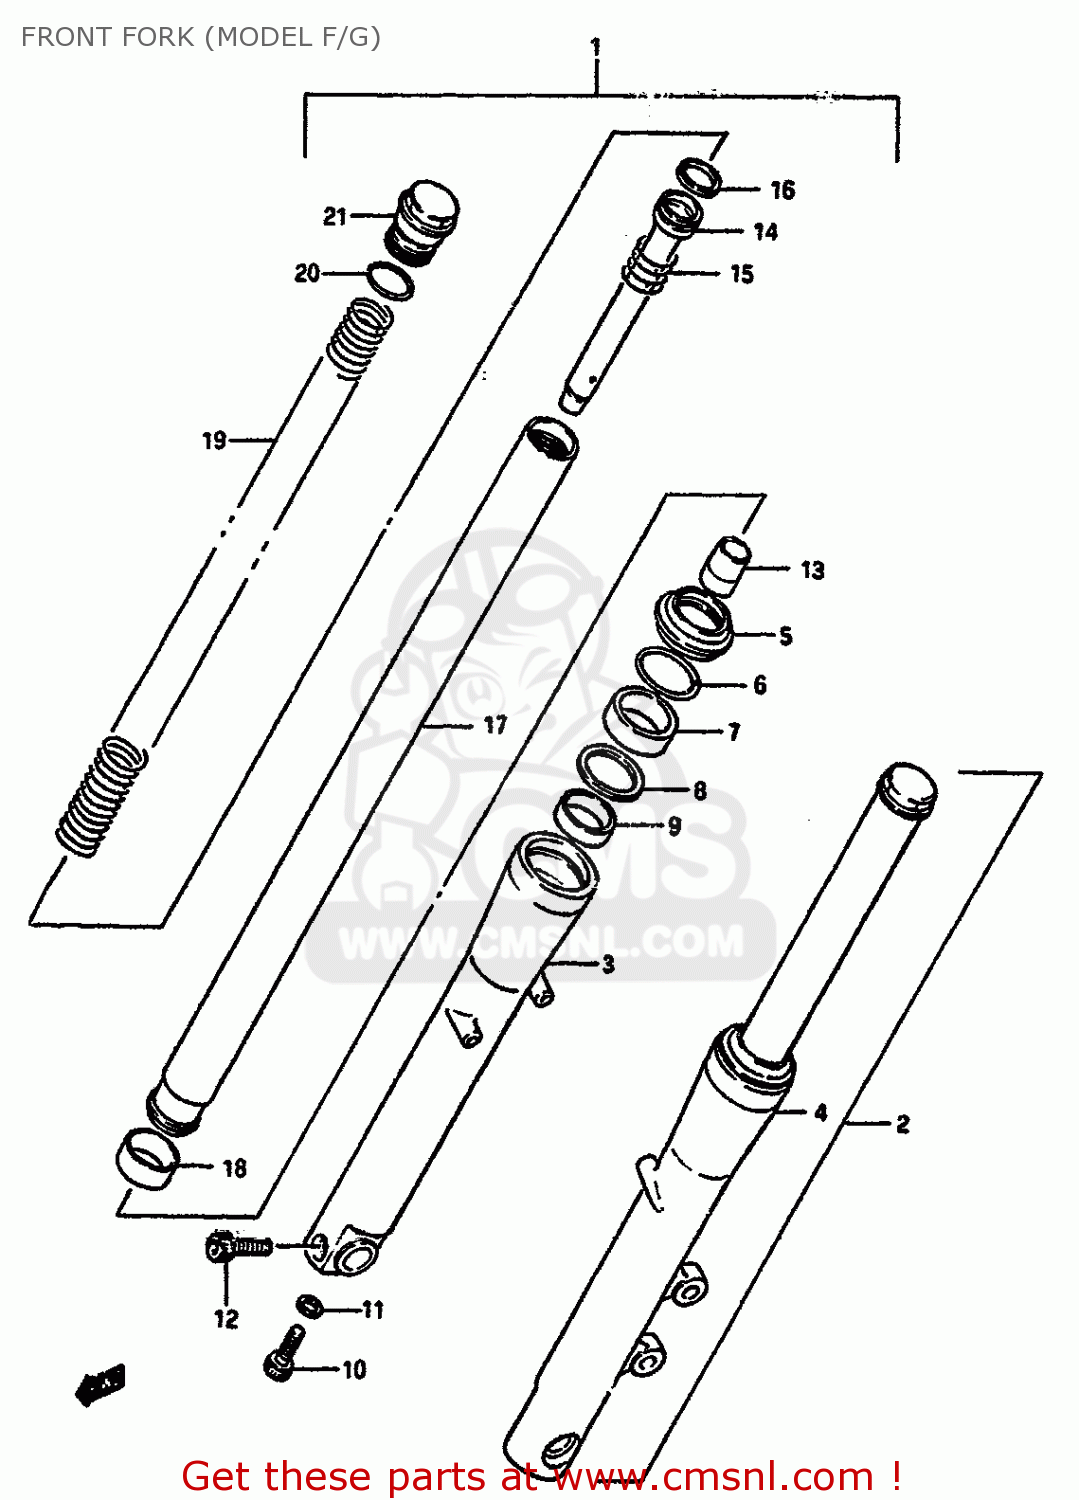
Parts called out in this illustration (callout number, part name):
1	DAMPER ASSEMBLY,RIGHT
2	DAMPER ASSEMBLY,LEFT
3	TUBE,OUTER,RIGHT
4	TUBE,OUTER,LEFT
5	SEAL,DUST
6	RING, STOPPER
7	OIL SEAL,FRONT FORK
8	SPACER,SEAL
9	BUSHING,GUIDE
10	BOLT(8X27)
11	GASKET (NAS)
12	BOLT, FRONT RH
13	PIECE,OIL LOCK
14	CYLINDER
15	SPRING,REBOUND
16	RING,PISTON
17	TUBE,INNER
18	PISTON
19	SPRING
20	O RING
21	BOLT
